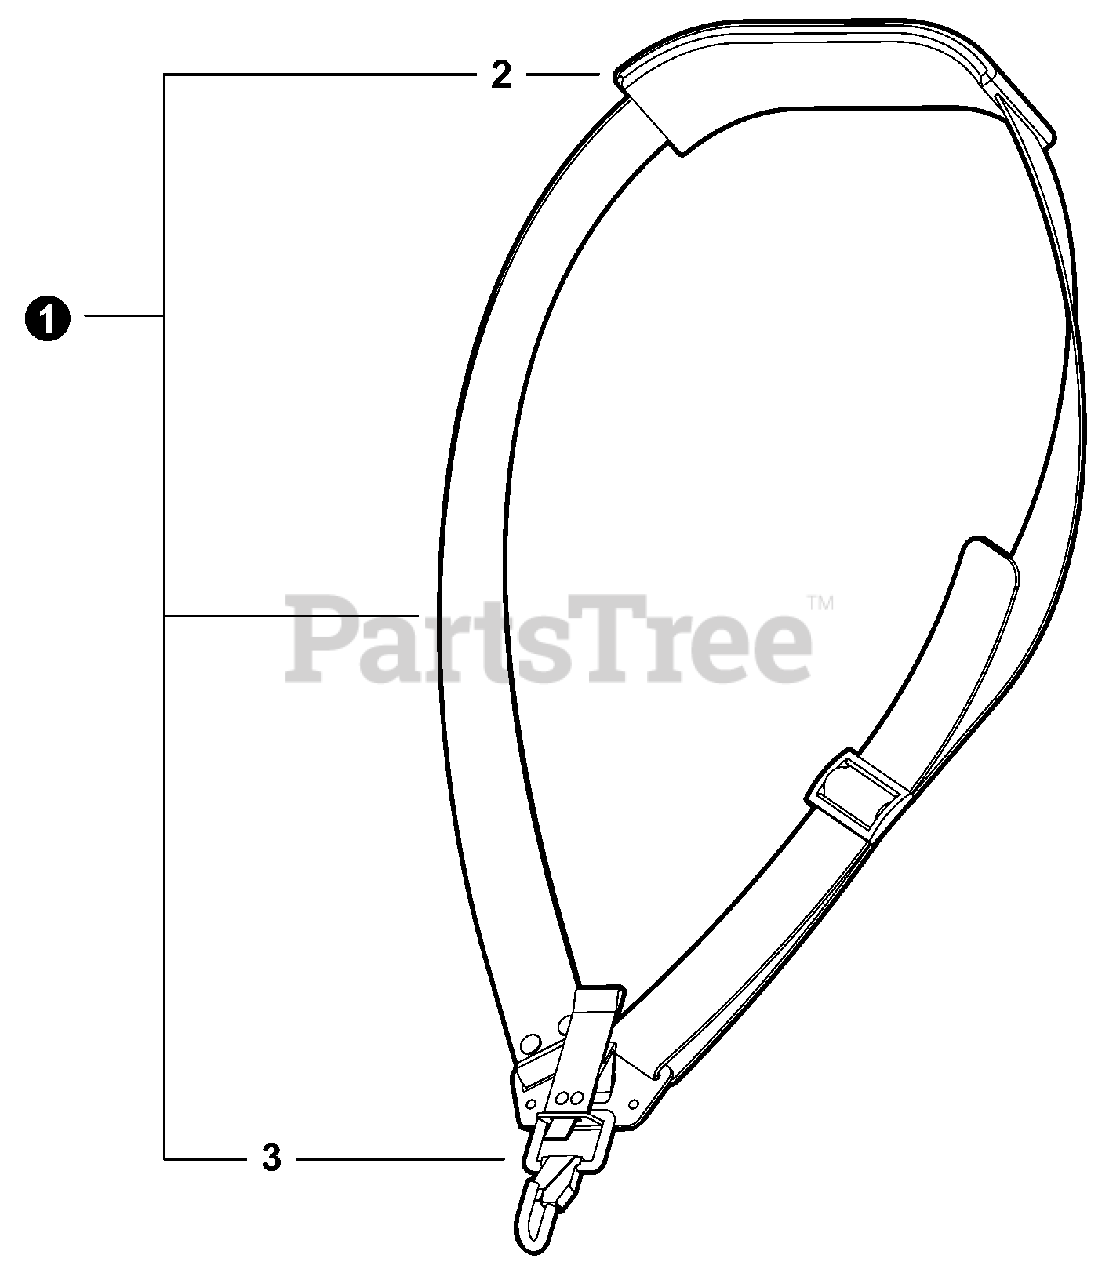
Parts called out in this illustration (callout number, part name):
1	HARNESS ASSY, SHOULDER
2	PAD, SHOULDER
3	HOOK, SNAP
